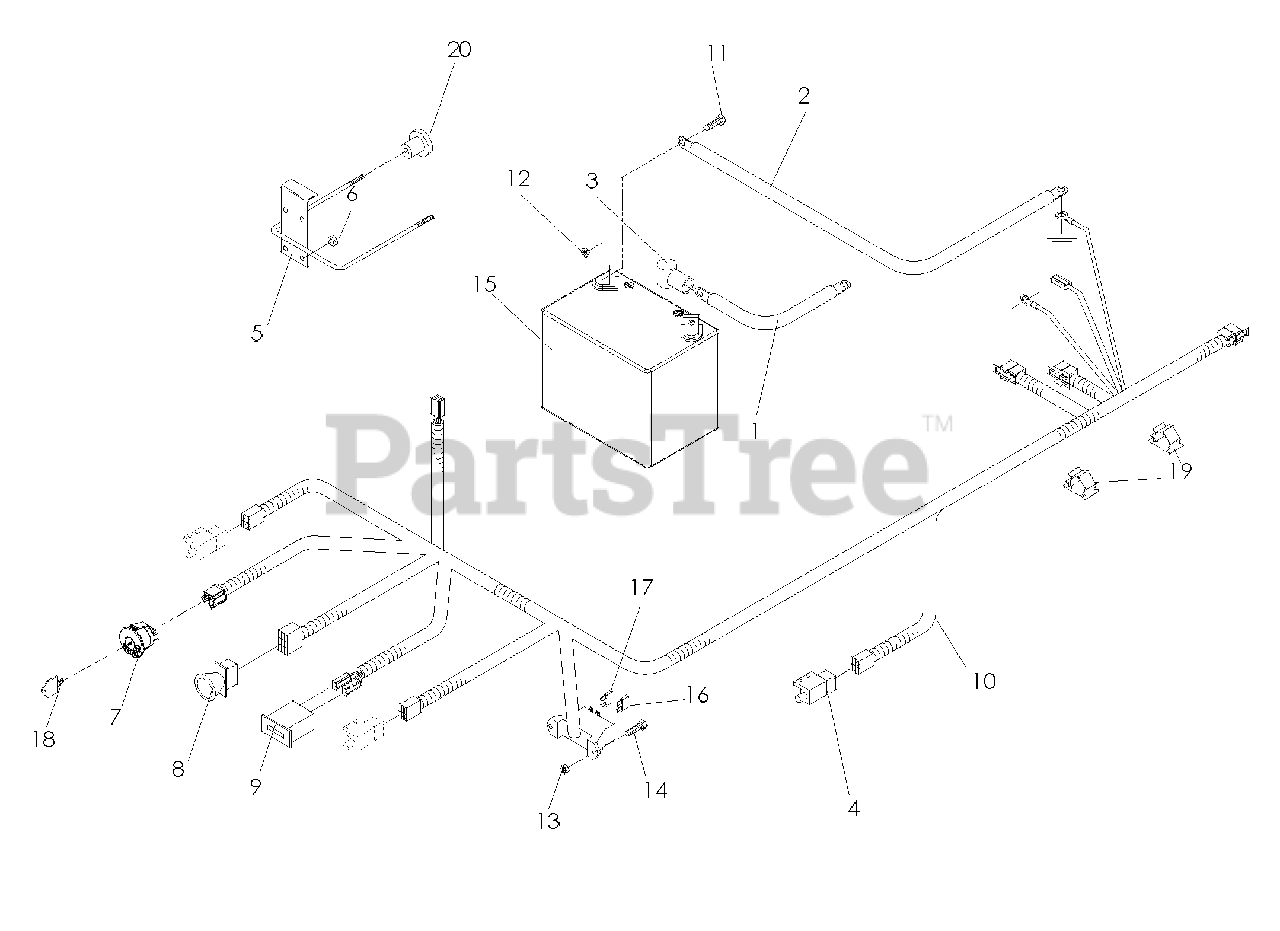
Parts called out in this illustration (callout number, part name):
1	CABLE, POSITIVE
2	CABLE, NEGATIVE
4	SWITCH, INTERLOCK
5	BATTERY HOLD DOWN
7	SWITCH, IGNITION
8	SWITCH, PTO
9	METER, HOUR
10	FRAME HARNESS
11	HCS 5/16-18 x 3/4
12	NUT 5/16-18 HEX NYLOC
13	NUT 10-24, NYLOC
14	SCREW 10-24 x 7/8
15	BATTERY, DRY
16	FUSE, 75 AMP, 32V, ATO
17	FUSE, 20 AMP, 32V, ATO
18	KEY, PADDED
19	CLIP, PUSH MOUNT
